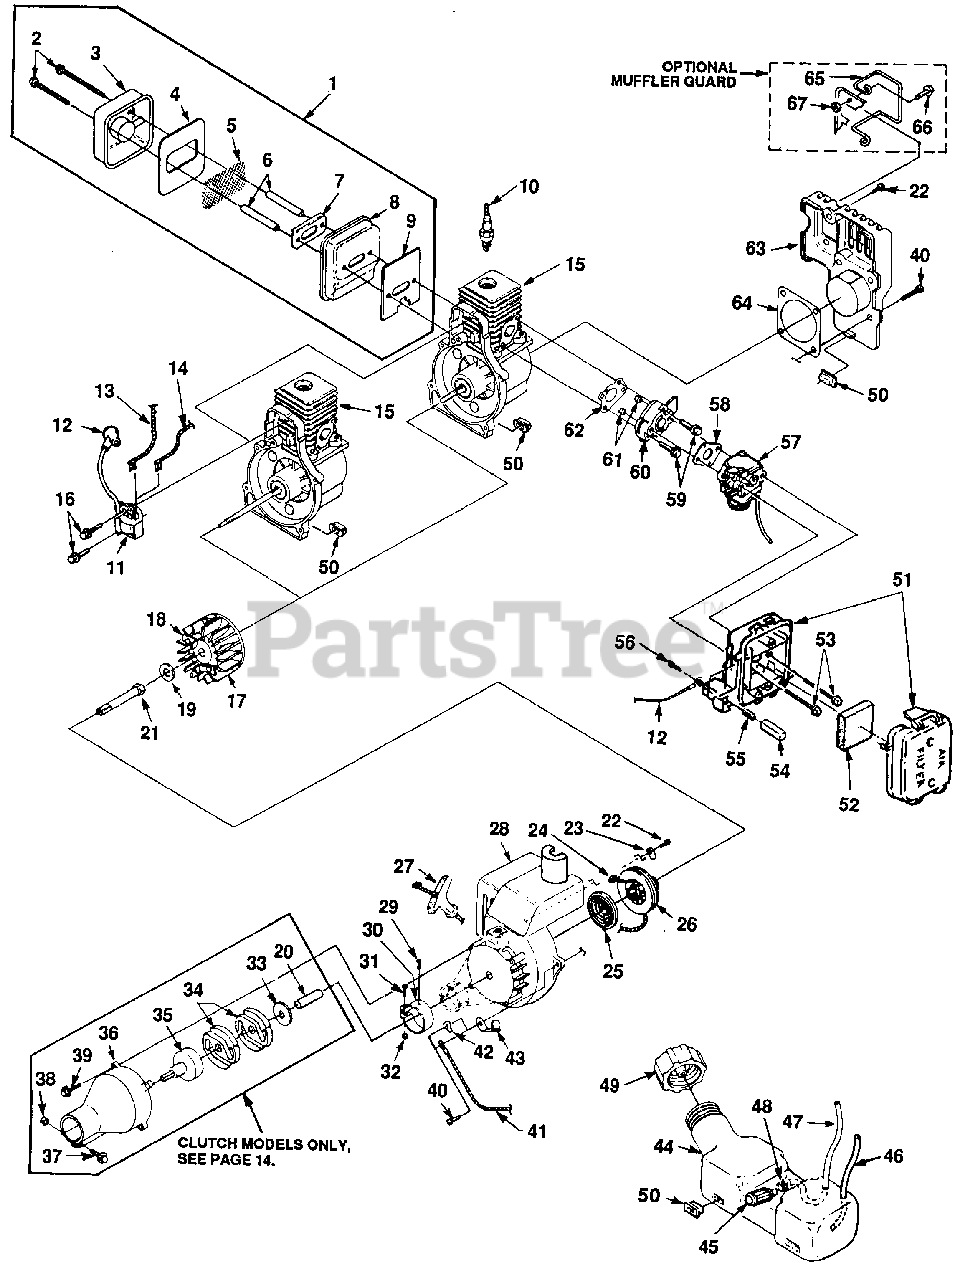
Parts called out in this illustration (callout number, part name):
1	MUFFLER- Complete
2	SCREW- Sems Hex Hd (10-24 X 2 1/2")
3	COVER- Muffler
4	BAFFLE- Muffler
5	SCREEN- Spark
6	SPACER- Muffler
7	PLATE- Reinforcing
8	BODY- Muffler
9	GASKET- Muffler
10	SPARK PLUG (DJ7Y)
11	MODULE- Ignition
12	TERMINAL- High-Tension
13	LEAD-Electrical (ST-185BC, GST-BC, ST-285BC, ST-385BC, HBC-18, HBC-30)
14	LEAD-Electrical (ST-155,SX-135,ST-175G,HLT-15,ST-275,GST,HGT,HLT-16
15	SHORT BLOCK
16	SCREW- Taptite (8-32 X 1")
17	ROTOR KIT (ST-185BC, GST-BC
17	ROTOR KIT (ST-285BC, ST-385BC, HBC-18, HBC-30)
17	ROTOR KIT (ST-155, SX-135,ST-175G,HLT-15,ST-275,GST,HGT,HLT-16,HLT-1
18	KIT- Starter Pawl
19	WASHER- Flat
19	WASHER- Flat (5/16") (ST-155,SX-135,ST-175G,HLT-15,ST-275,HLT-18,HLT-1
20	SPACER
21	CONNECTOR- Drive (ST-155,SX-135,ST-175G,HLT-15,ST-275,GST,HGT,HLT-16
22	SCREW- Plastite (#10 X 1/2")
23	BRACKET- Retaining
24	ROPE- Starter (42")
25	SPRING & CONTAINER
26	PULLEY- Starter
27	GRIP- Starter
28	HOUSING- Engine (ST 155,SX-135,ST-175G,HLT-15,ST-275,GST,HGT,HLT-16)
28	HOUSING-Engine (ST-185BC,GST-BC,ST-285BC,ST-385BC,HBC-18,HBC-30)
29	SCREW- Pan Hd. (#10 X 3/8")
30	CLAMP
31	SCREW- Hex Sems (10-24 X 3/8")
32	NUT- Square
33	WASHER- Clutch (ST-185BC, GST-BC, ST-285BC, ST-385BC, HBC-18, HBC-30)
34	CLUTCH (ST-185BC, GST-BC) (ST-285BC, ST-385BC, HBC-18, HBC-30)
35	CONNECTOR & DRUM (ST-185BC, GST-BC)
36	TUBE ADAPTOR (ST-185BC, GST-BC, ST-285BC, ST-385BC, HBC-18, HBC-30)
37	SCREW- Sems Hex Hd (10 24 X 1 1/4")
38	NUT (10-24)
39	SCREW- Sems Hex Hd (10-24 X 7/8")
40	SCREW- Taptite (10-24 X 3/4")
41	LEAD- Ground
42	TERMINAL
43	BRACKET Cable
44	TANK- Fuel
45	FILTER- Fuel
46	TUBING- Rubber (8")
47	TUBING- Rubber (8")
48	CLAMP- Wire
49	FUEL CAP
50	BUMPER- Rubber
51	AIR FILTER BOX
52	FILTER- Air
53	SCREW (10-24 X 2 1/4")
54	BUTTON- Switch
55	SPRING- Compression
56	SCREW- Plastite (#6)
57	CARBURETOR KIT
58	GASKET Carburetor
59	SCREW- Taptite (10-24 X 1")
60	HEAT DAM
61	NUT (10-24)
62	GASKET- Heat Dam
63	CRANKCASE COVER
64	GASKET- Crankcase Cover
65	WIRE GUARD KIT
66	SCREW- Hex Sems (10-24 X 1/2")
67	NUT (10-24)
